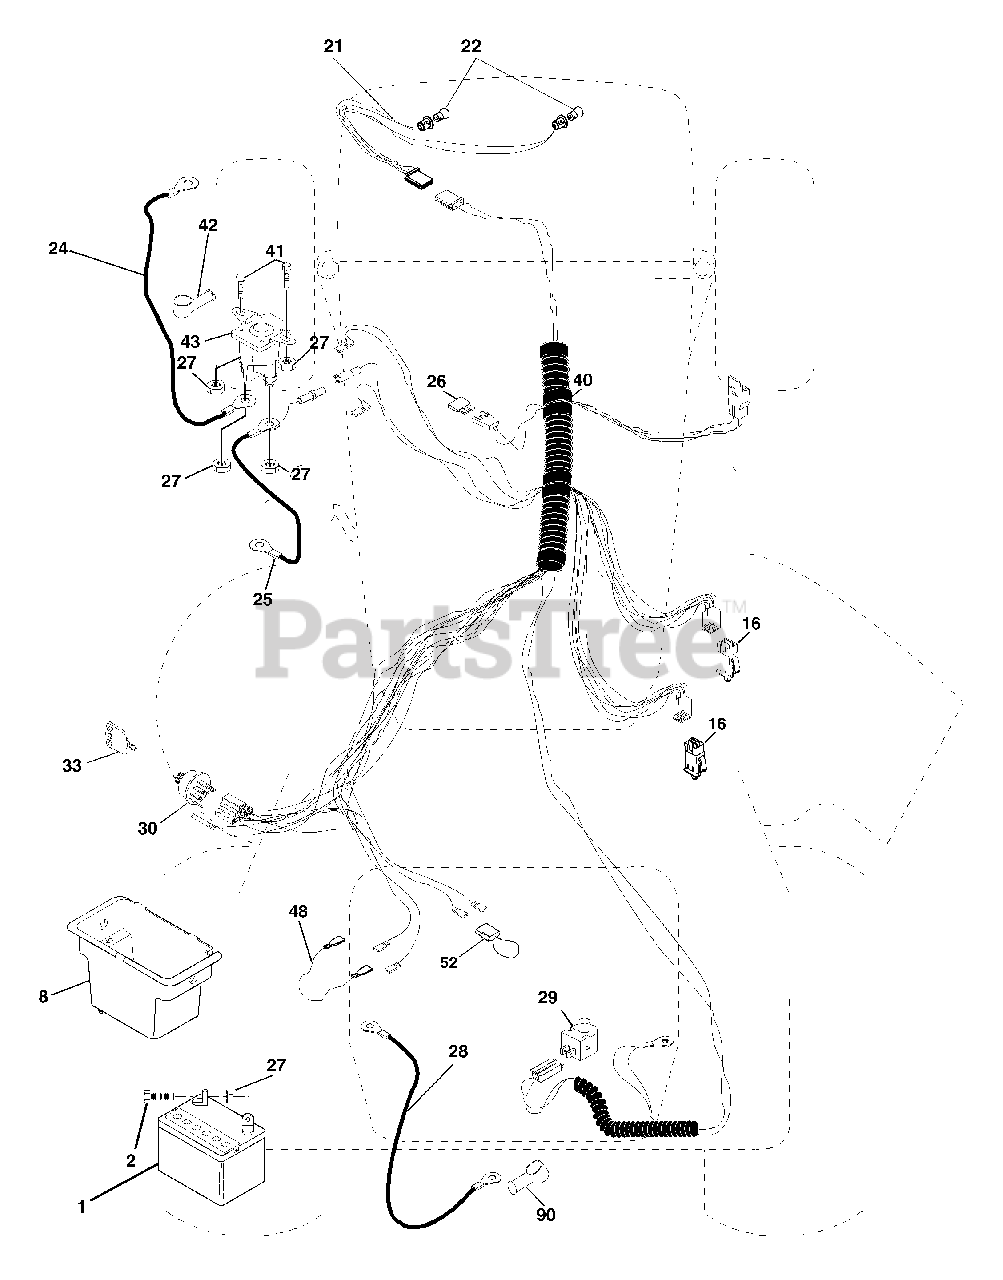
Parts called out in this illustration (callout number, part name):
1	Battery
2	Bolt Hex Hd 1/4-20unc X 3/4
8	Box Battery
16	Switch Interlock
21	Harness Asm Light W/4152j
22	Bulb Light #1156
24	Cable Battery 6 Ga 11" red
25	Cable Battery
26	Fuse 20 AMP
27	Nut Keps Hex 1/4-20 Unc
28	Cable Ground 6 Ga 12" black
29	Switch Plunger Nc Gray
30	Switch Ign
33	Key Ign
40	Harness Ign
41	Bolt Blk Fin Hex 1/4-20
42	Cover Terminal Red
43	Solenoid
48	Adapter Ammeter
52	Protection Wire Loop
